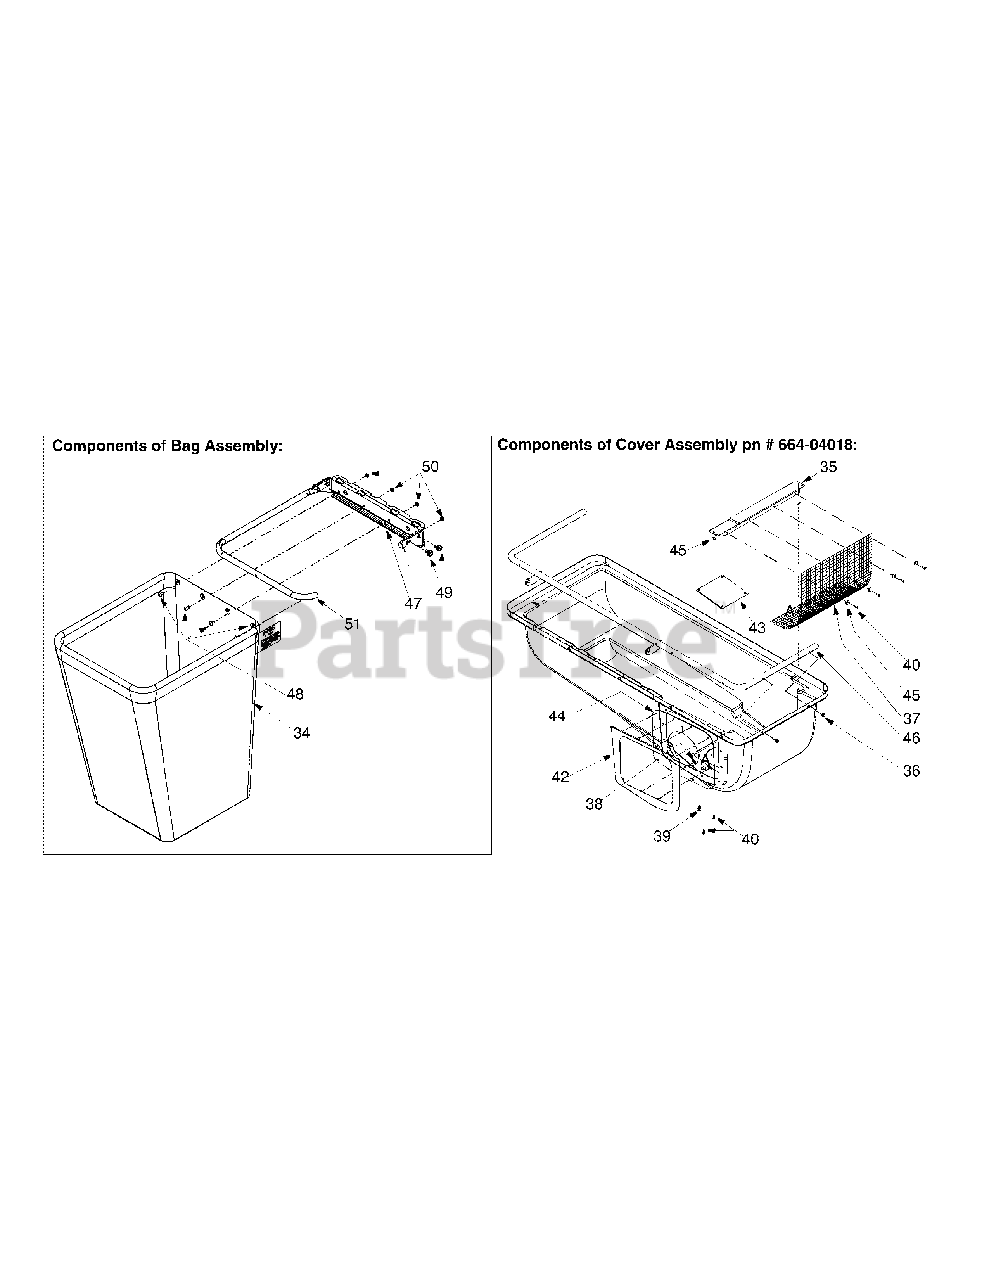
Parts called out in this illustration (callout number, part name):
39	Ratchet Clip
40	Pop Rivet
42	Retainer Seal
43	Plastic Plate
44	Grass Bag Seal
45	Flat Washer
46	Hinge Bracket
47	Bag Hanger Bracket
48	Machine Screw
49	TT Screw 5/16-18 x 0.625
50	Hex Sems Nut
51	Tube: Grass Bag Frame
